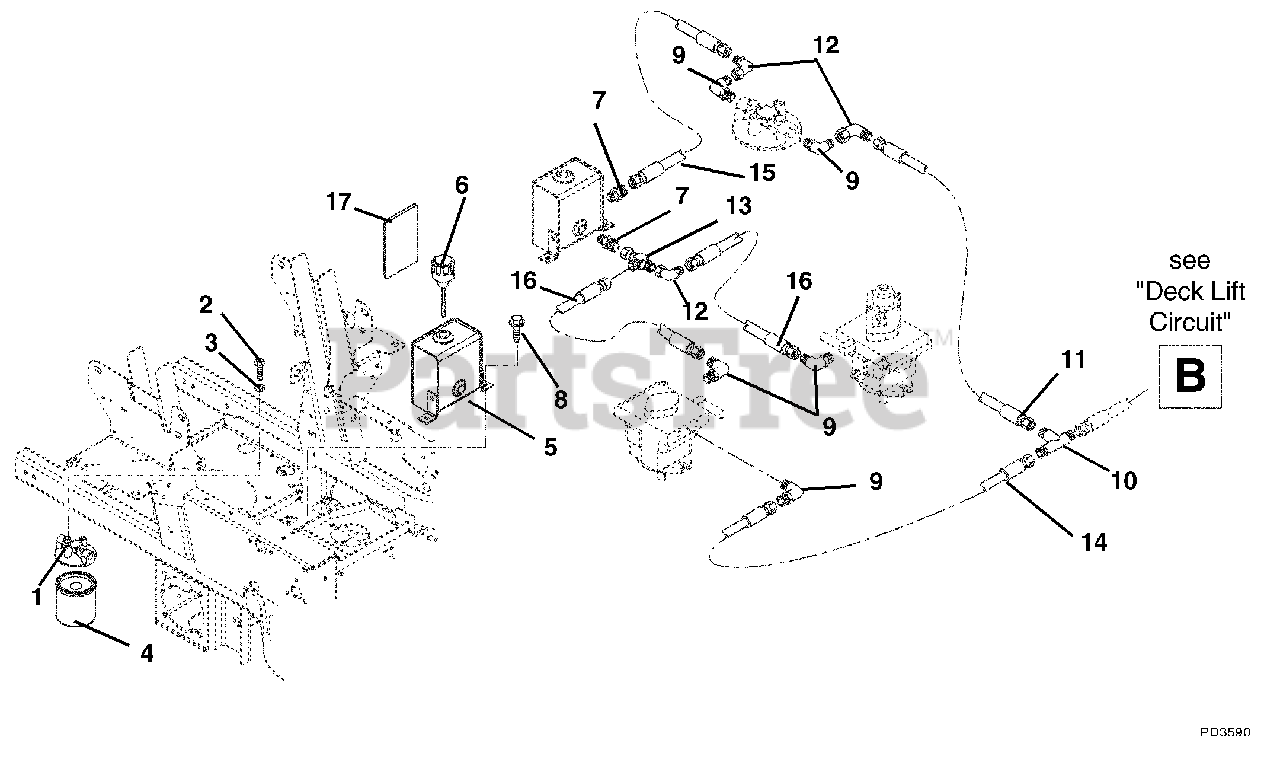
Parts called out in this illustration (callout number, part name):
1	Head-Filter
2	Bolt-Hex .25-20 x .50 Grade 5
3	Washer-Locking .25 x .062
4	Oil Filter
5	Tank-Hydraulic
6	Hydraulic Tank Dipstick
7	Adapter, Straight
8	Screw-Tapping .38-16 x .50 Hex Washer Head
9	Adapter
10	Adapter, Tee .56-18
11	Hose-Hydraulic
12	Adapter
13	Adapter, Pipe
14	Hose, Hydraulic
15	Hose,Hydraulic Valve To Tank
16	Hose, Hydraulic
17	Shield, Heat 5.50 x 4.50
